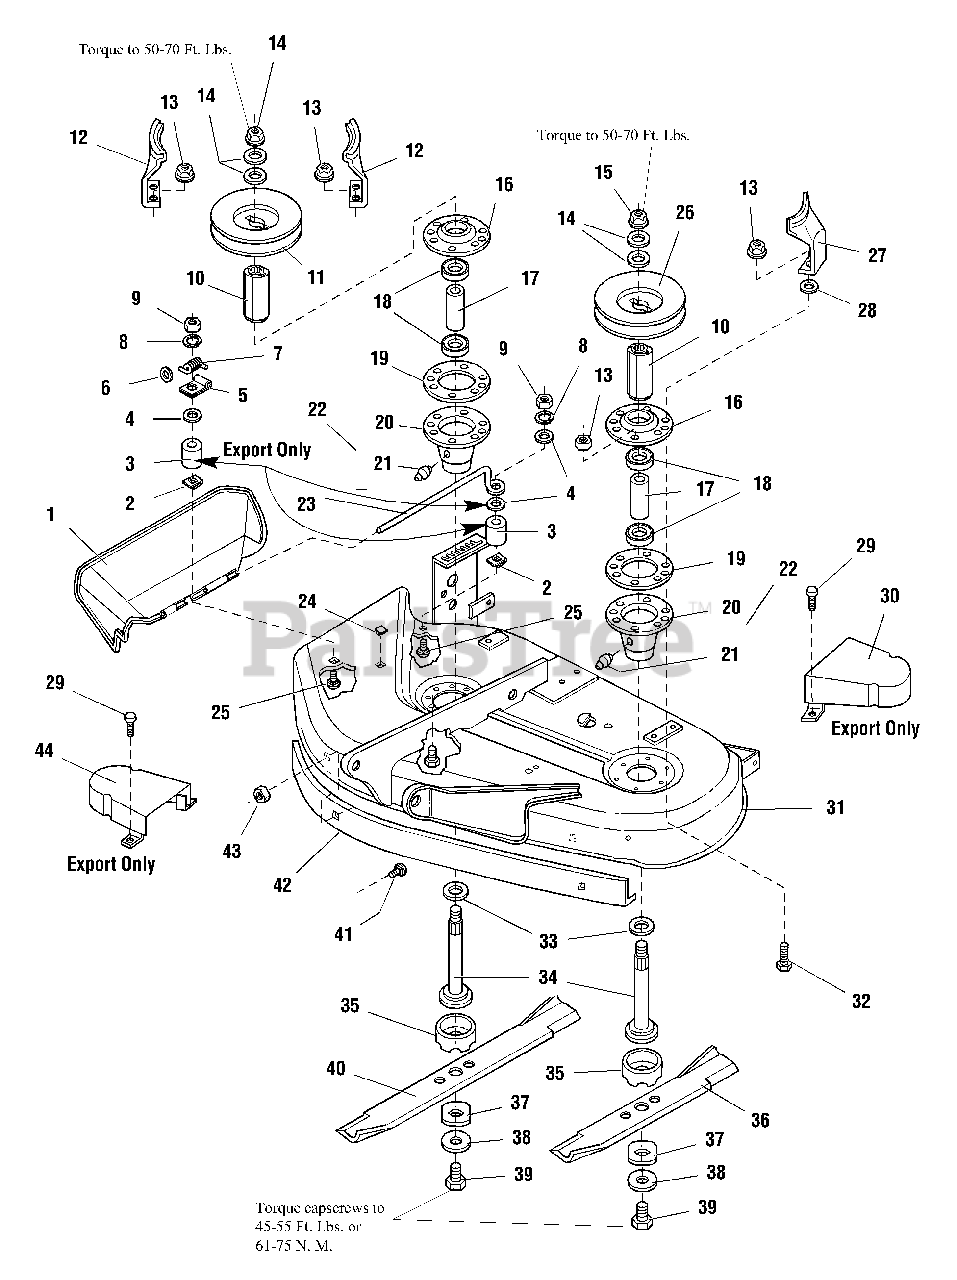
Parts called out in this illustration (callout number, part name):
1	DEFLECTOR, Plastic
2	NUT, Push On
3	SPACER
4	WASHER, 1/4
6	WASHER, Plain, 5/16
8	LOCKWASHER, 1/4
9	NUT, Hex, 1/4-20
11	PULLEY, Deck Drive, R.H. 5.25
12	STOP, Belt, R.H.
13	NUT, Hex, Flange Whiz Lock, 5/16-18
14	WASHER, Belleville
15	NUT, Hex, Flange, 9/16-8
16	COVER, Arbor Housing
19	GASKET, Foam
20	HOUSING ARBOR, Bottom
21	FITTING, Grease
22	HOUSING ASSEMBLY, Arbor Bottom, w/Lube Fitting
23	ROD, Deflector, Front
24	PLUG, Plastic
25	CARRIAGE BOLT, 1/4-20 x 1 1/2
26	PULLEY, Deck Drive, L.H. 4.0
27	STOP, Belt, L.H.
28	WASHER, Plain, 3/8
29	CAPSCREW, Taptite Hex Washer Hd, 5/16-18 x 3/4
30	COVER & SUPPORT ASSEMBLY, Arbor L.H.
31	HOUSING ASSEMBLY, 38" Mower (Cardinal Red)
32	CAPSCREW, Taptite Hex Washer Hd, 5/16-18 x 1
34	SHAFT, Arbor
35	SHIELD, Grass, Lower
36	BLADE, Mower, 16-1/8"
37	WASHER, Hex
38	WASHER, Spring
39	CAPSCREW, Hex, Hd., 7/16-14 x -1/4
40	BLADE, Mower, 22-1/4"
41	CARRIAGE BOLT, 5/16 - 18 x 3/4 G5
42	BAFFLE, Anti-Blowout
43	NUT, Hex Flange Lock, 5/16-18
44	COVER & SUPPORT ASSEMBLY, Arbor R.H.
